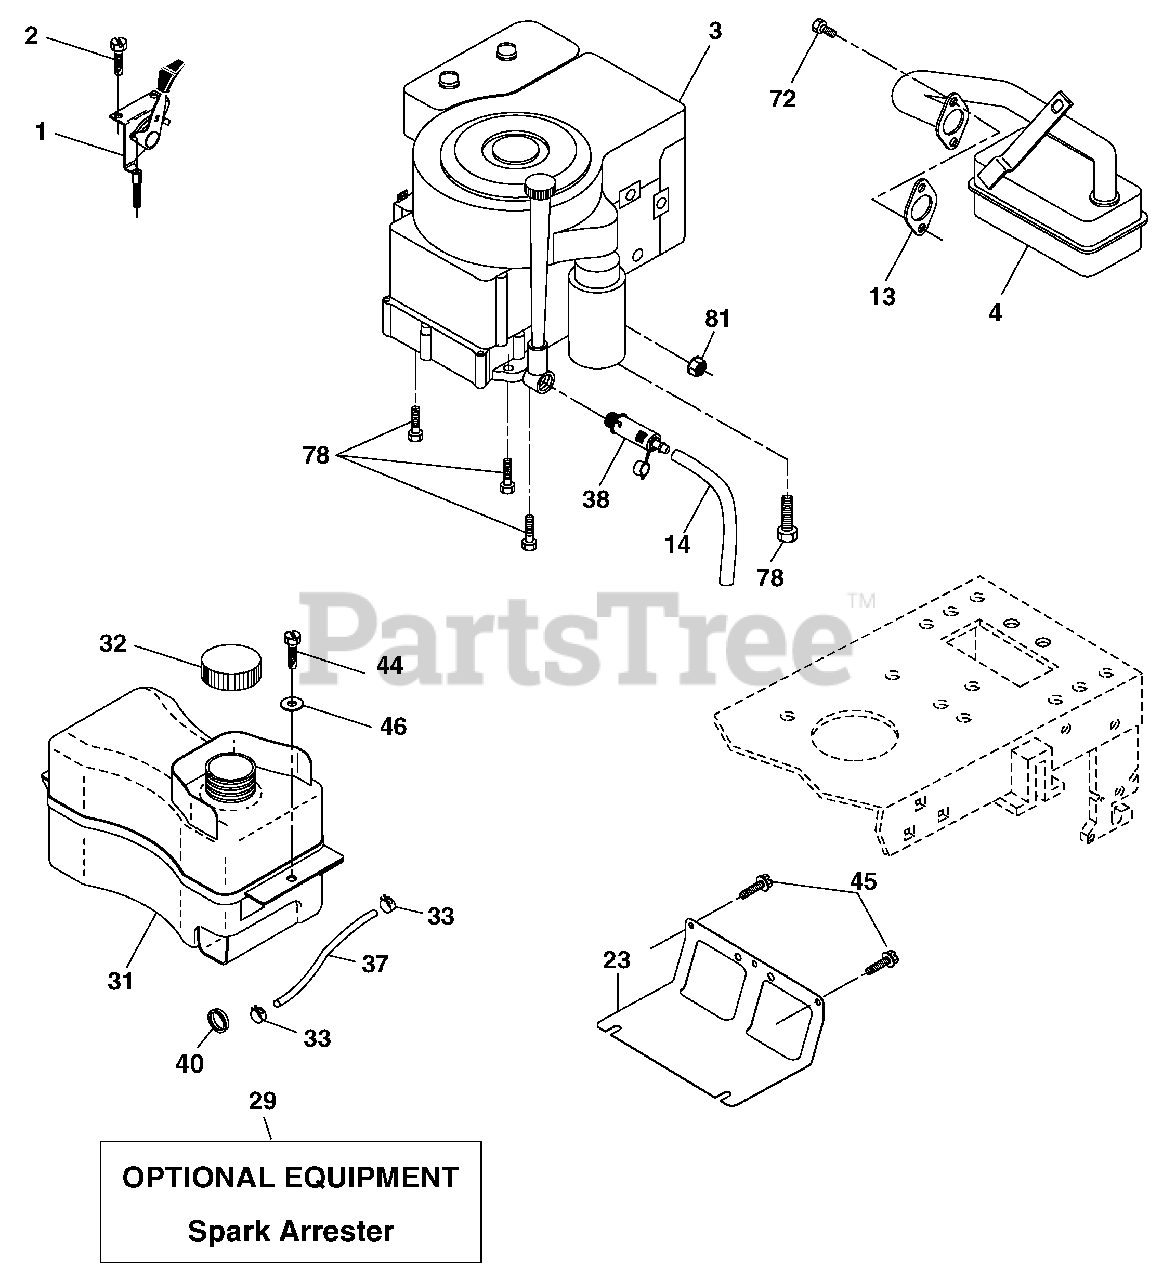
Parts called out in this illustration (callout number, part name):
1	Control Th/ch Flag
2	Screw Hex Thd Cut 1/4-20 x 1/2
4	Muffler Exhaust B&S
13	Gasket Eng 1 313 Id Tin Plated
14	Tube Drain Oil Easy
23	Shield BRN/DBR Guard
29	Kit Spark Arrestor (Flat Scrn)
31	Tank Fuel Front
32	Cap Asm Fuel
33	Clamp Hose
37	Line Fuel
38	Plug Drain Oil
40	Bushing Snap Nyl Blk Fuel Line
44	Screw Thdrol 1/4-20 x 3/4
45	Screw Hex Wsh Thdrol 3/8-16
46	Washer 9/32 x 7/8 x 16 Ga.
72	Screw Socket Head 5/16-18 x 3/4
78	Screw 3/8-16 x 1-1/4
81	Nut Keps Hex 1/4-20 unc
